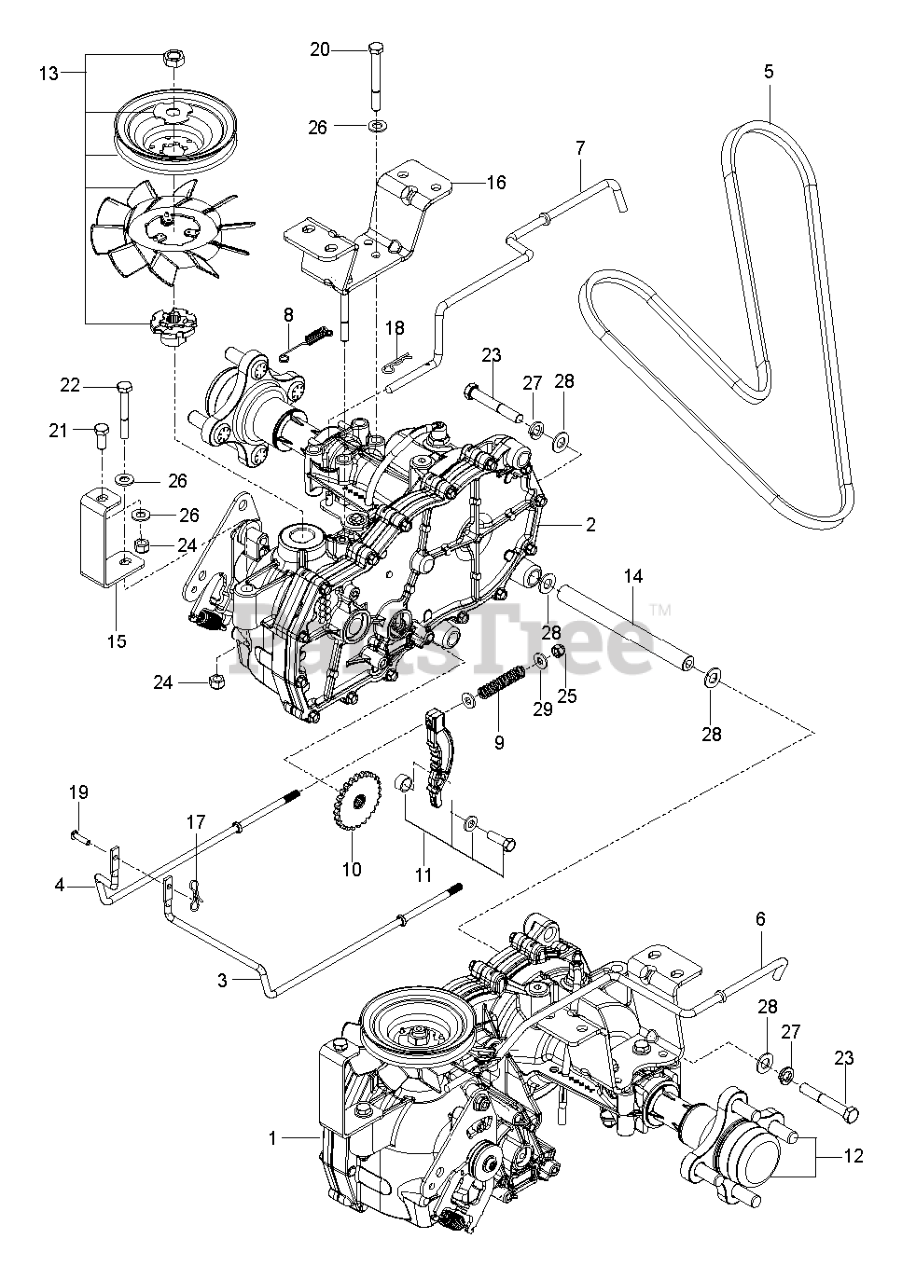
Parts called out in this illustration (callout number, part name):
1	HG_EZT, LT
2	HG_EZT, RT
3	LINKAGE.BRAKE.LT
4	LINKAGE, BRAKE RT
5	BELT, HYDRO PUMP
6	ROD.BYPASS.RZ.LH
7	ROD.BYPASS.RHT
8	SPRING.ROD.BYPASS.EZT
10	HG_DISC COG BRAKE 51635
11	HG_KIT BRAKE ARM (EZT)
12	HG_KIT, HYDRO-GEAR HUB
13	KIT FAN/PULLEY 72137
14	SPACER TUBE EZT
15	SUPPORT.FRONT.TRANS.PNTX431
16	BRACKET.EZT.MOUNT.REAR.PNTX431
17	PIN COTTER;LOCKING;BOWTIE;1IN
18	HAIRPIN #2
19	PIN.CLEVIS.3/16X.475
21	BOLT.FIN.HEX.5/16-18X3/4
22	BOLT.FIN HEX 5/16-18UNC X2 1/4
23	SCREW.HEX HEAD.38-16 X 2.5
24	NUT.71038.31-18.HEX.NYLOCK
25	NUT.1/4-20.HEX.NYLOC.ZD
26	WASHER
27	LOCKWASHER
28	WASHER
